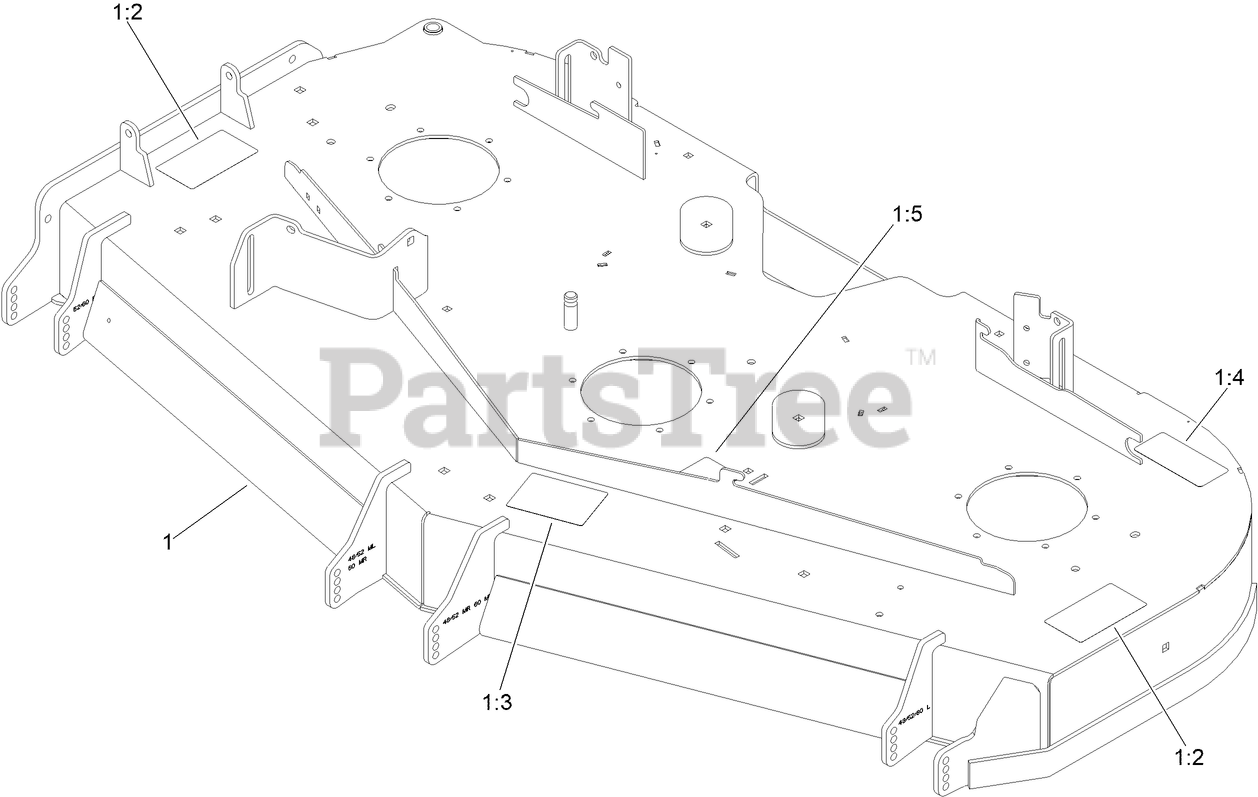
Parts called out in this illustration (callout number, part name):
1	ASM-DECK W/DECALS
1:2	DECAL-DANGER
1:3	DECAL-SCALP, ANTI
1:4	DECAL-TORQUE, BLADE BOLT
1:5	DECAL-ROUTING, BELT
